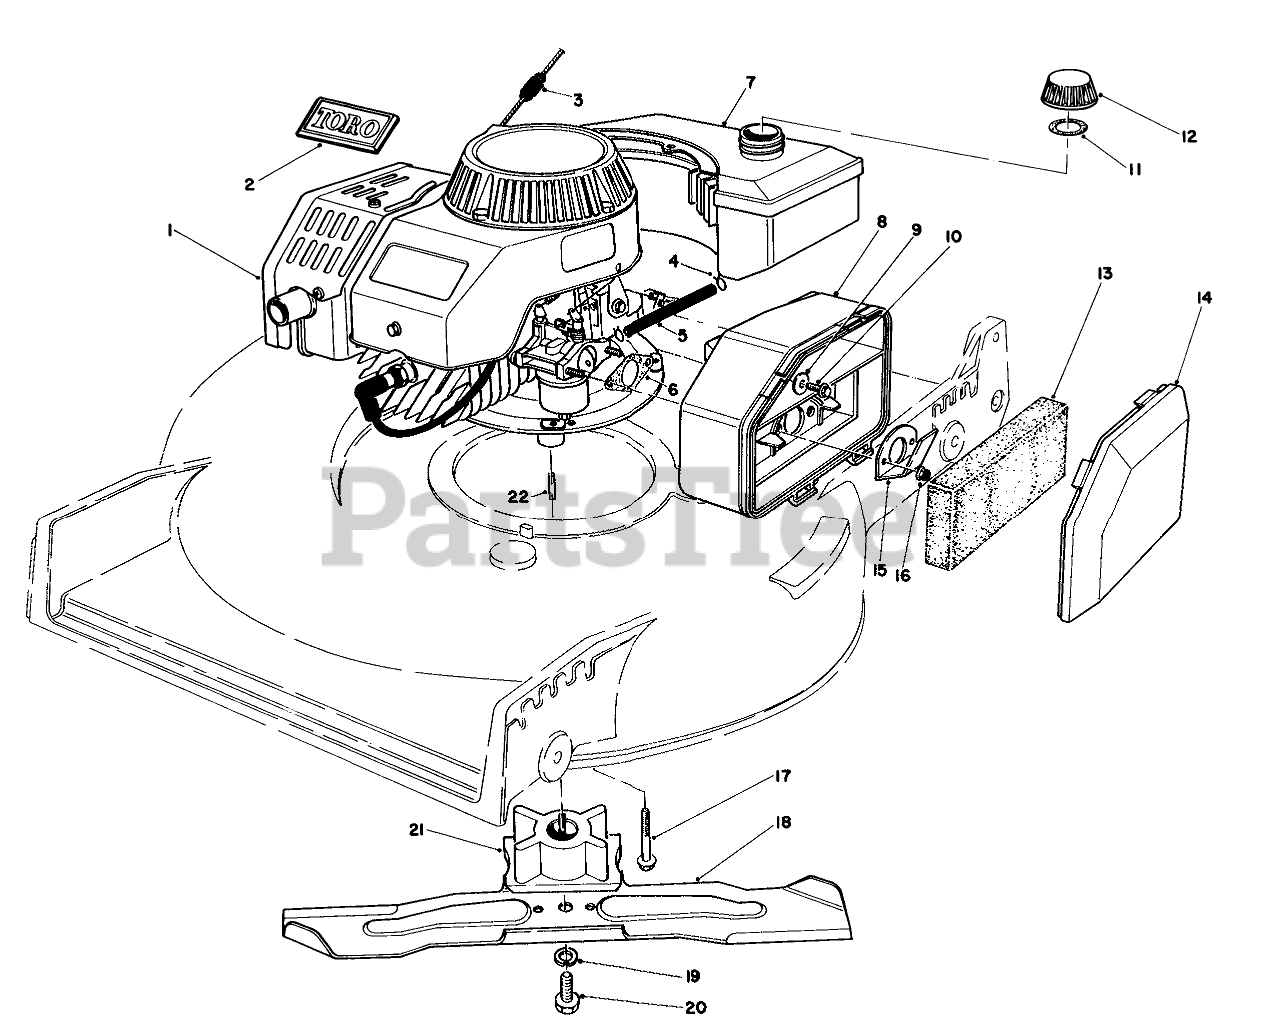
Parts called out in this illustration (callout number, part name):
1	Engine
2	TORO LOGO PLT
3	STOP-ROPE
4	CLAMP-HOSE
5	FUEL LINE
6	GASKET-AIR CLEANER
7	Gas Tank Assembly
8	AIR CLEANER
9	WASHER-FLAT
10	SCREW-HH
11	GAS CAP GASKET
12	Gas Cap Assembly (Incl. Ref. #11)
13	FILTER
14	AIR CLEANER COVER
15	SPIT BACK DEFLECTOR
16	NUT-LOCK
17	SCREW-HHF
18	BLADE-21in
19	WASHER-LOCK
20	SCREW-BLADE
21	Retainer Blade
22	KEY-SQUARE
